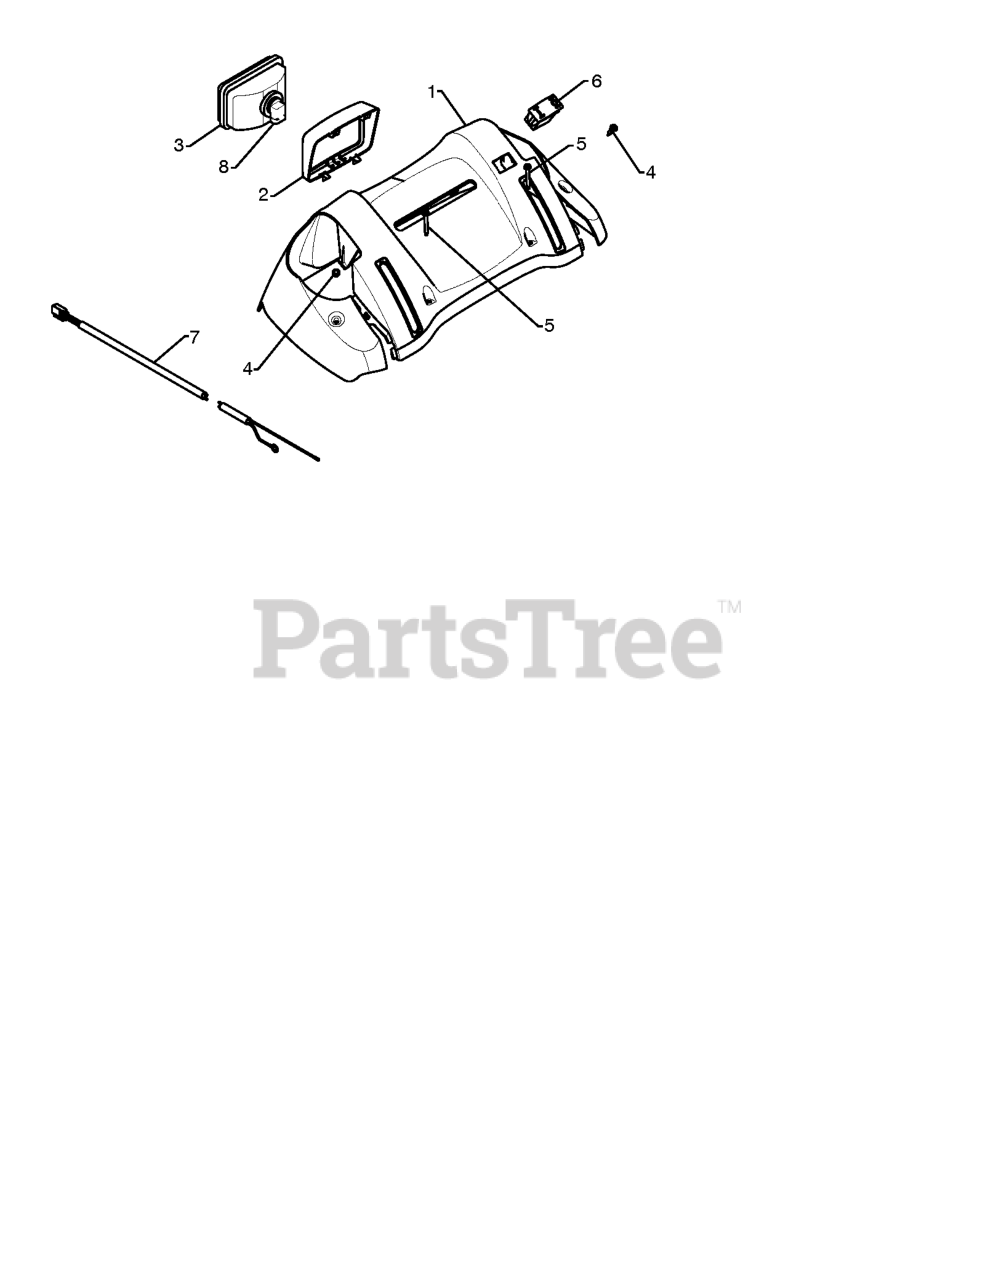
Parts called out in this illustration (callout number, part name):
1	PANEL.CONSOLE.
2	BEZEL.HEADLIGHT
3	HEADLIGHT.HALOGEN.SNOW
4	SCREW, HEX HEAD, TAPPING
5	SCREW, HEX HD TAPPING #10-24 1
6	SWITCH.HEATED.GRIP
7	HARNESS.WIRE.LIGHT/GRIP.SNOW
8	BULB.HEADLIGHT.HALOGEN.
